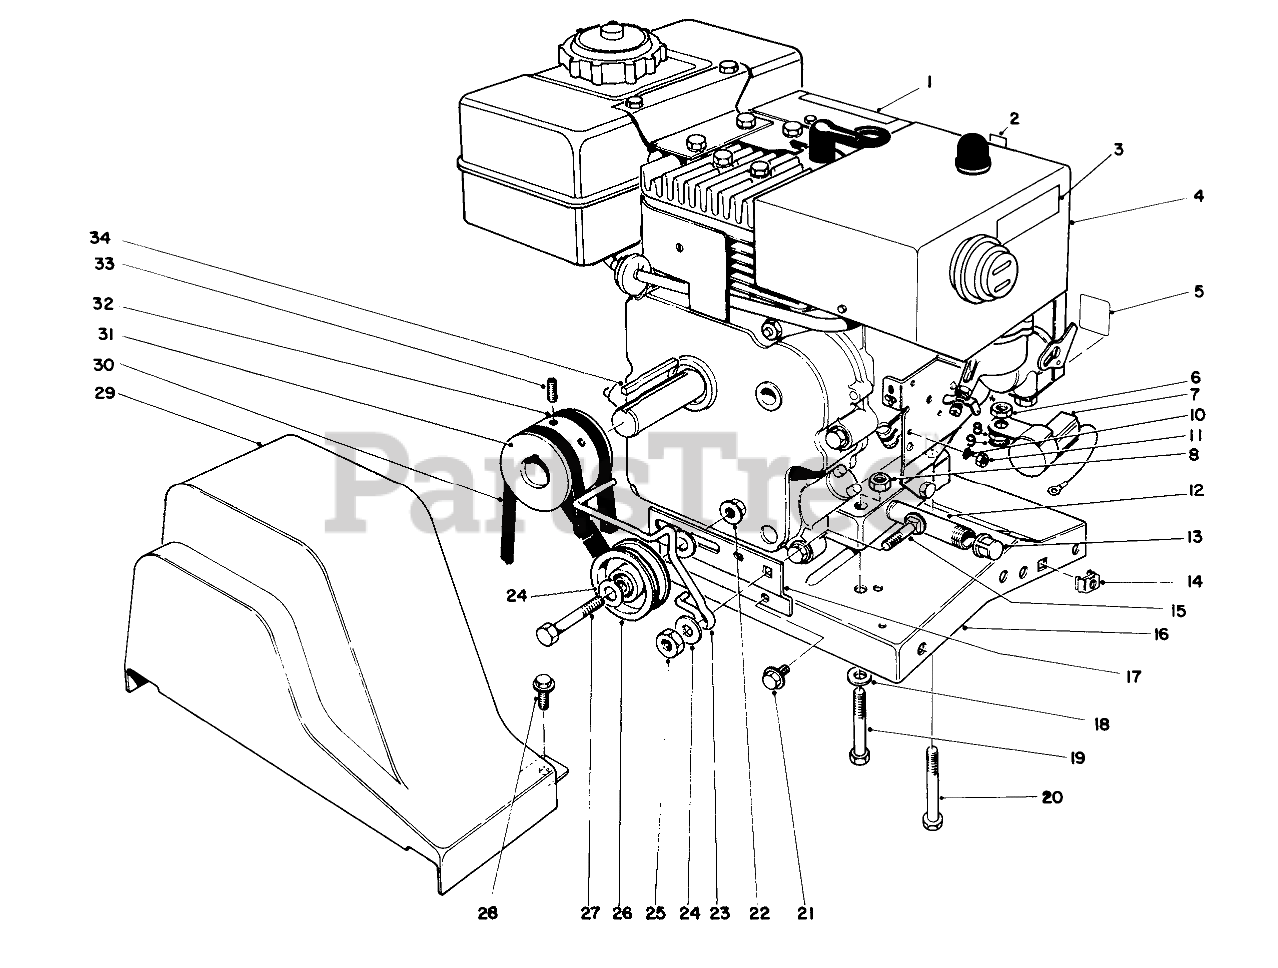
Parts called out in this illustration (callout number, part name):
1	HAZARDS CAUTION DECAL
2	Decal-Primer
3	Decal
5	Decal-Choke
6	NUT-HEX, SIDE DEFORM
7	INTERLOCK MODULE
8	NUT-LOCK, NI
9	WASHER-LOCK, INTERNAL
10	WASHER-LOCK/INT
11	NUT-LOCK
12	NIPPLE-PIPE
13	CAP-PIPE
14	RETAINER NUT
15	SCREW-CARR
16	Base-Engine
17	BELT IDLER BRKT
18	WASHER-PLAIN
19	SCREW-HH
20	SCREW-HH
21	SCREW-HWHTF
22	NUT-HHF, WHIZ
23	BELT GUIDE
24	WASHER-FLAT
25	NUT-LOCK, NI
26	PULLEY B
27	SCREW-HH
28	SCREW-HWH
29	BELT GUARD
30	V-BELT
31	ENGINE PULLEY
32	V-BELT
33	SETSCREW
